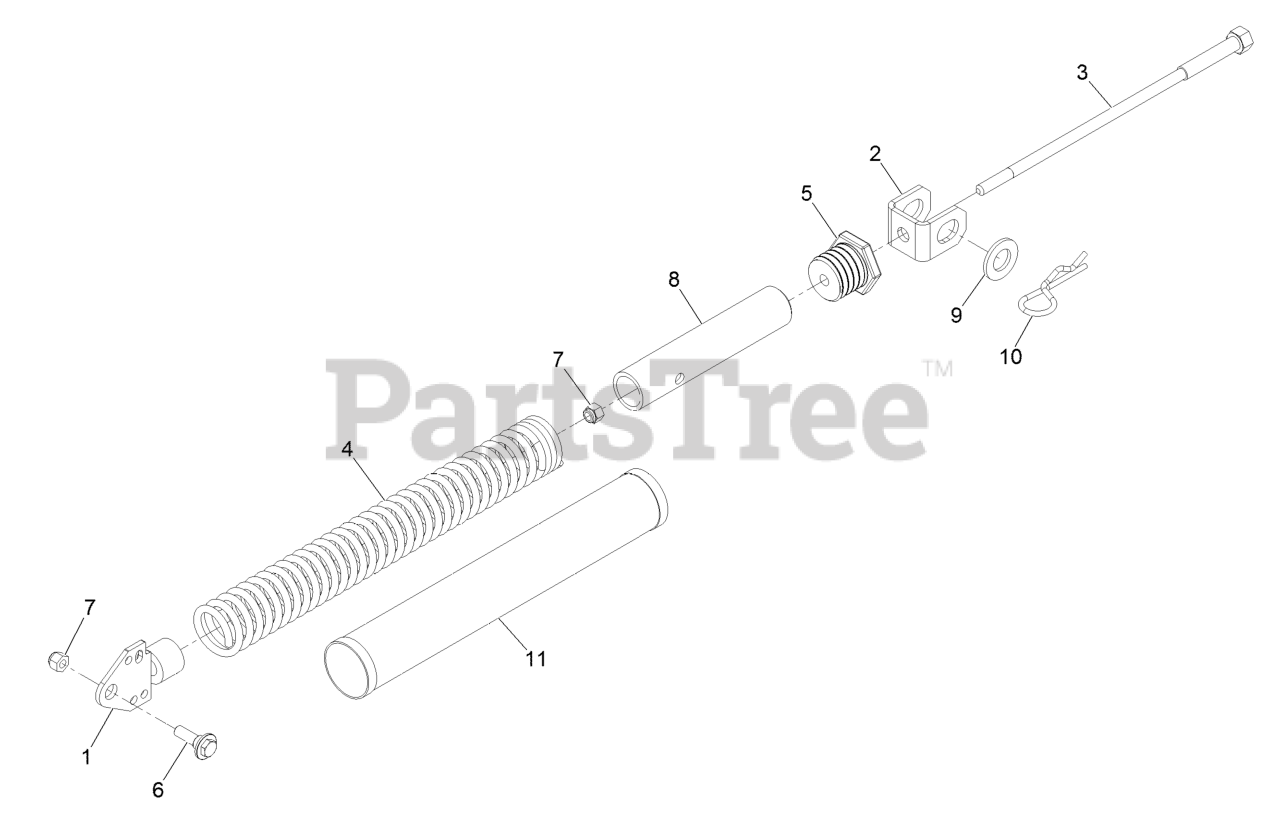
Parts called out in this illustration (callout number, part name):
1	TENSIONER-SPRING
2	MOUNT-LIFT ASSIST, DECK
3	SHAFT-ADJUSTMENT, SPRING
4	SPRING-EXTENSION
5	PLUG-ADJUSTER, SPRING
6	SCREW-SHOULDER, HWH
7	NUT-LOCK, NI
8	SPRING-TUBE
9	WASHER-FLAT
10	PIN-CUT HEIGHT
11	COVER-SPRING, DECK
